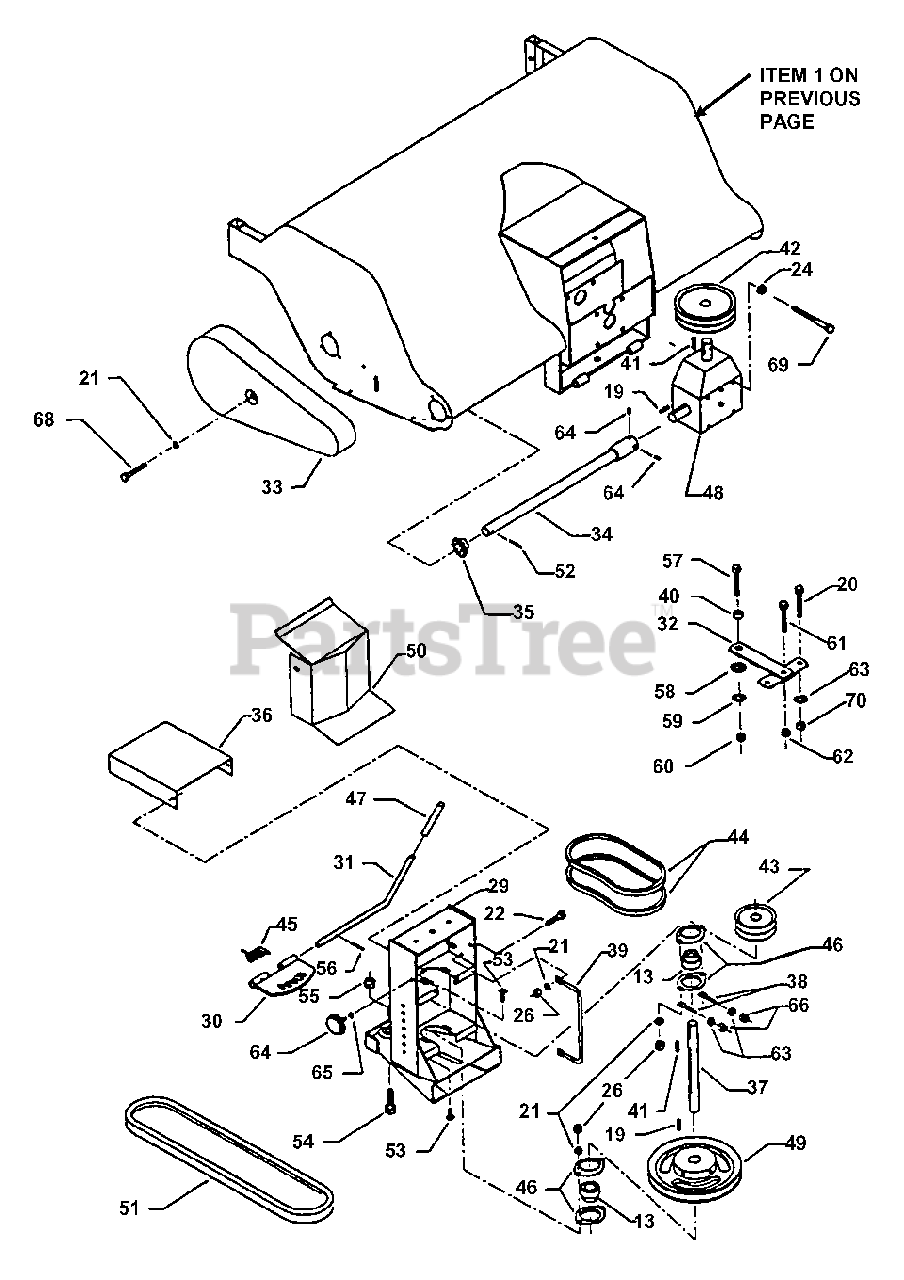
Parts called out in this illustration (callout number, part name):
1	HOUSING
13	BEARING w/Locking Collar
19	KEY, 1/4" Square x 1-1/4"
20	BOLT, 5/16-18 x 1" Hex
21	WASHER, 5/16" Lock
22	BOLT, 5/16-18 x 3/4" Hex
24	WASHER, 3/8" Lock
26	NUT, 5/16-18 Hex
29	HITCH, Female
30	ANGLE ADJUSTMENT
32	COUPLER, Upper
33	GUARD, Chain
34	DRIVE SHAFT, Chain
35	SPROCKET
36	GUARD, Upper Pulley
37	SHAFT, Pulley
38	TENSIONER, Twin Belt
39	BELT GUIDE
40	BUSHING, Upper
41	KEY, 1/4" Square x 1-1/2" long
42	PULLEY, Twin Belt (2MA60)
43	PULLEY, Twin Belt (2MA40)
44	V-BELT (AX26)
45	SPRING, Torsion
46	BEARING FLANGE (2 holes)
47	HANDLE, Plastic
48	GEARBOX
49	DRIVE PULLEY (MB65)
50	GUARD, Rear Pulley
51	DRIVE BELT, SP Models with Kohler Engine (B-57)
52	ROLL PIN, 1/4" Dia. x 1-1/4" long
53	BOLT, 5/16-18 x 3/4" Square Neck Carriage, Grade 5
54	BOLT, 3/4-10 x 2-3/4" Hex
55	NUT, 3/4-10 Stover
57	BOLT, 7/16-14 x 1-3/4" Hex
58	WASHER, 1/2" Flat
59	WASHER, 7/16" Lock
60	NUT, 7/16-14 Hex
61	BOLT, 7/16-14 x 1-1/4" Hex
62	NUT, 7/16-14 Hex Nyloc
63	WASHER, 3/8" Flat
65	WASHER, 5/16" External Tooth Lock
66	NUT, 5/16-18 Stover
68	BOLT, 5/16-18 x 2-3/4" Hex
69	BOLT, 3/8-16 x 4-1/2" Hex
70	NUT, 5/16-18 Hex Nyloc
